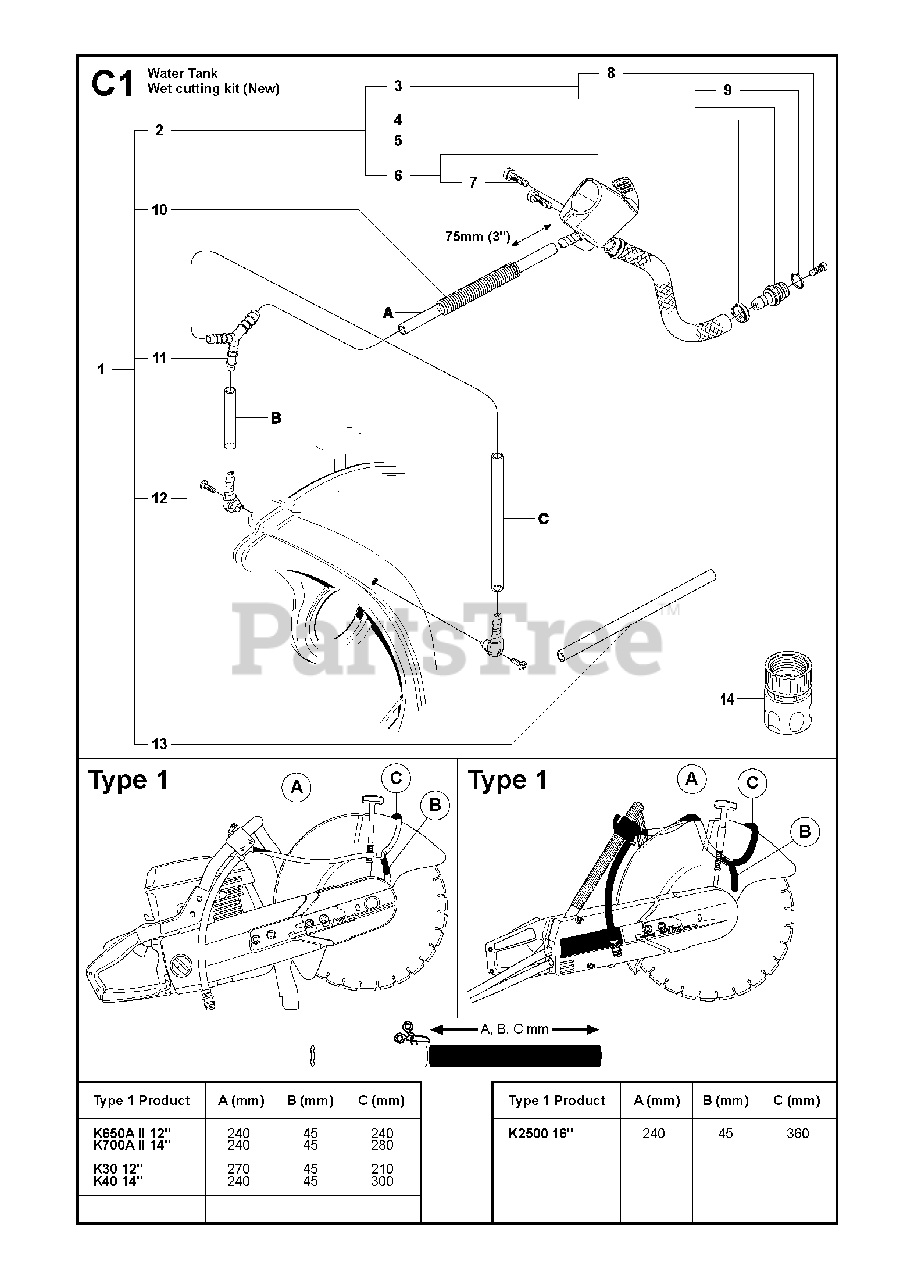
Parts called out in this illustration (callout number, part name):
1	HOSE KITIncl. 2, 10 - 13
2	VALVE ASSYIncl. 3 - 6
3	NIPPLEIncl. 8
4	HOSE CLAMP
5	HOSEL=230mm
6	VALVE ASSYIncl. 7
9	O-RING
10	PROTECTIVE SPRING
13	HOSE
14	COUPLER
